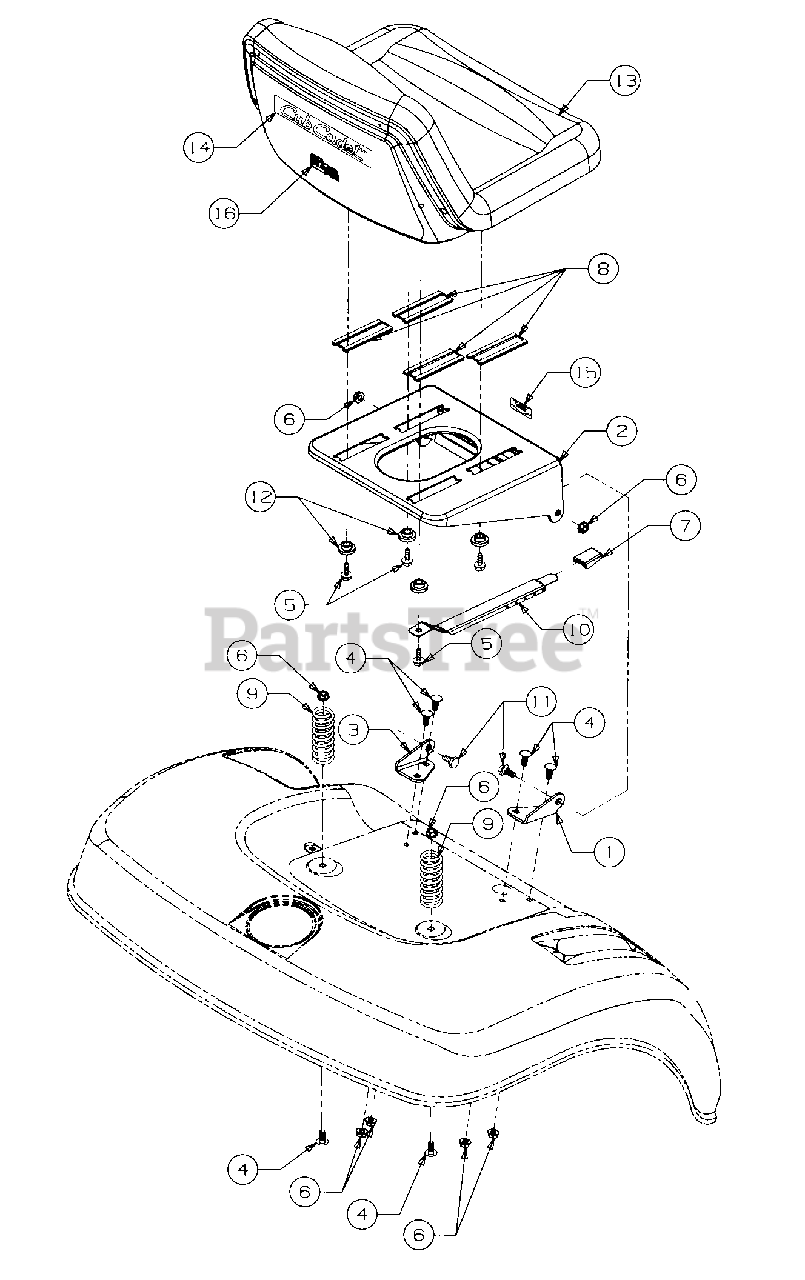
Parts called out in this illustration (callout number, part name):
1	Bracket, RH Seat Pivot
2	Seat, Base
3	Bracket, LH Seat Pivot
4	Bolt, Carriage, 5/16-18 x .75
5	Screw, Wsh Hd Tap, 5-16-18 x .75
6	Nut, Hex Flange Lock, 5/16-18
7	Knob, Seat Adjuster
8	Slide, Seat
9	Spring, Comp, 1.9 OD x 2.4 Lg
10	Adjuster, Seat
11	Bolt, Shoulder
12	Spacer, Shoulder
13	Seat, Medium Back
14	Graphic, Seat Back
15	Graphic, Seat Adjuster
16	Graphic, Made in USA
